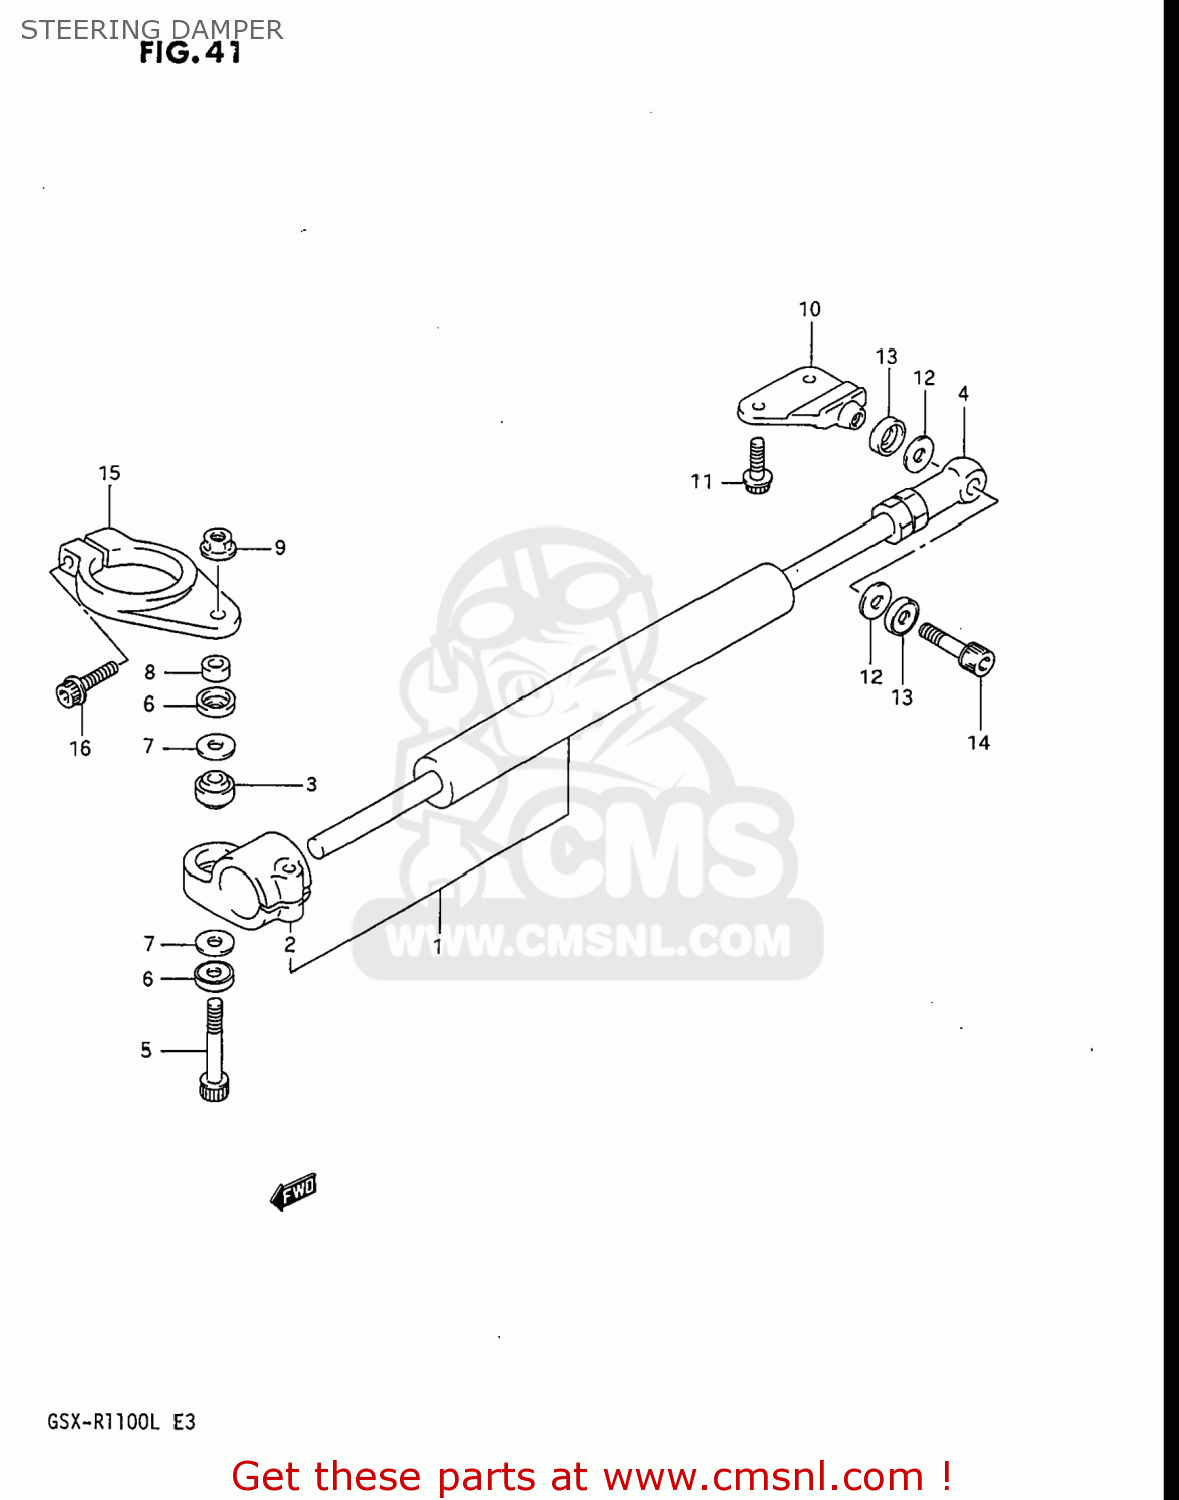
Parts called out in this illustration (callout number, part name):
1	DAMPER ASSEMBLY,STEERING
2	BRACKET,STEERING DAMPER
3	BEARING(8X18X11)
4	PILLOW BALL,ROD END
5	BOLT
6	7
7	SHIM
8	SPACER (8.4X14X6)
9	NUT
10	BOSS,STEERING DAMPER
11	BOLT
12	SHIM
13	14
14	BOLT, FRONT RH
15	BRACKET,STEERING DAMPER FORK
16	BOLT,BRACKET
